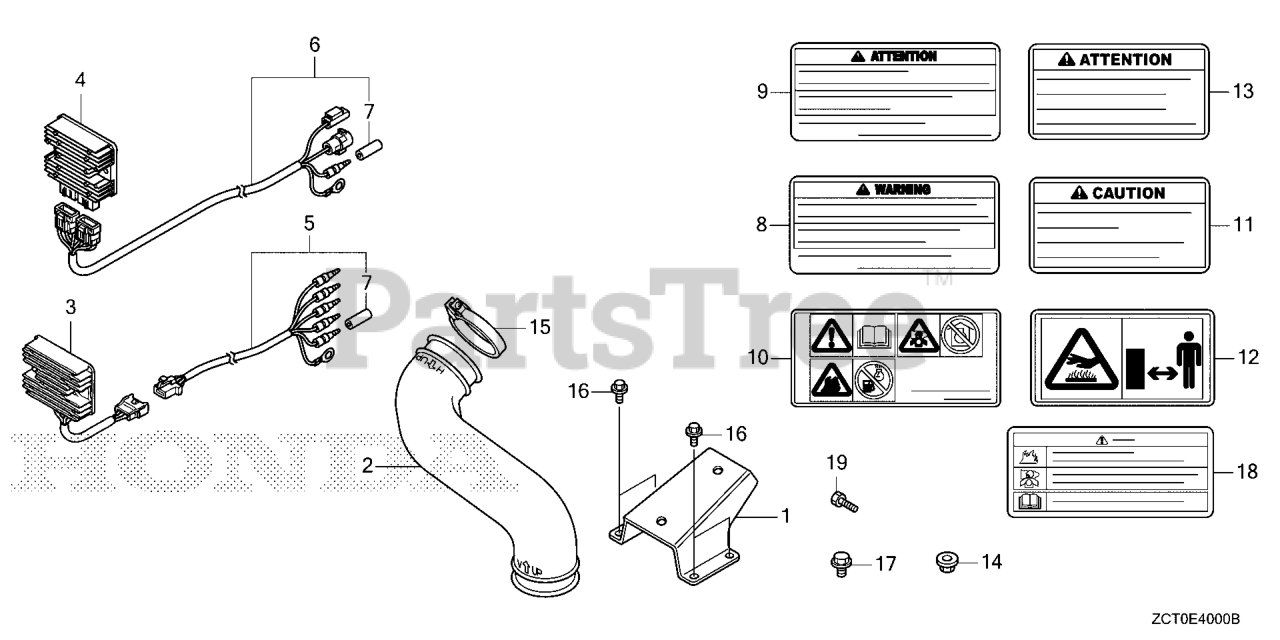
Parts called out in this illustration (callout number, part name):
3	RECTIFIER ASSY., REGULATOR (20A)
5	SUB-WIRE HARNESS ASSY.
7	PLUG, CONNECTOR (OUTER) (ENGINE NO.)
9	MARK, OPERATOR CAUTION (FRENCH)
10	MARK, OPERATOR CAUTION (PICTOGRAPH)
11	MARK, EX. CAUTION (ENGLISH)
12	MARK, EX. CAUTION (PICTOGRAPH)
13	MARK, EX. CAUTION (FRENCH)
14	NUT, FLANGE (8MM)
